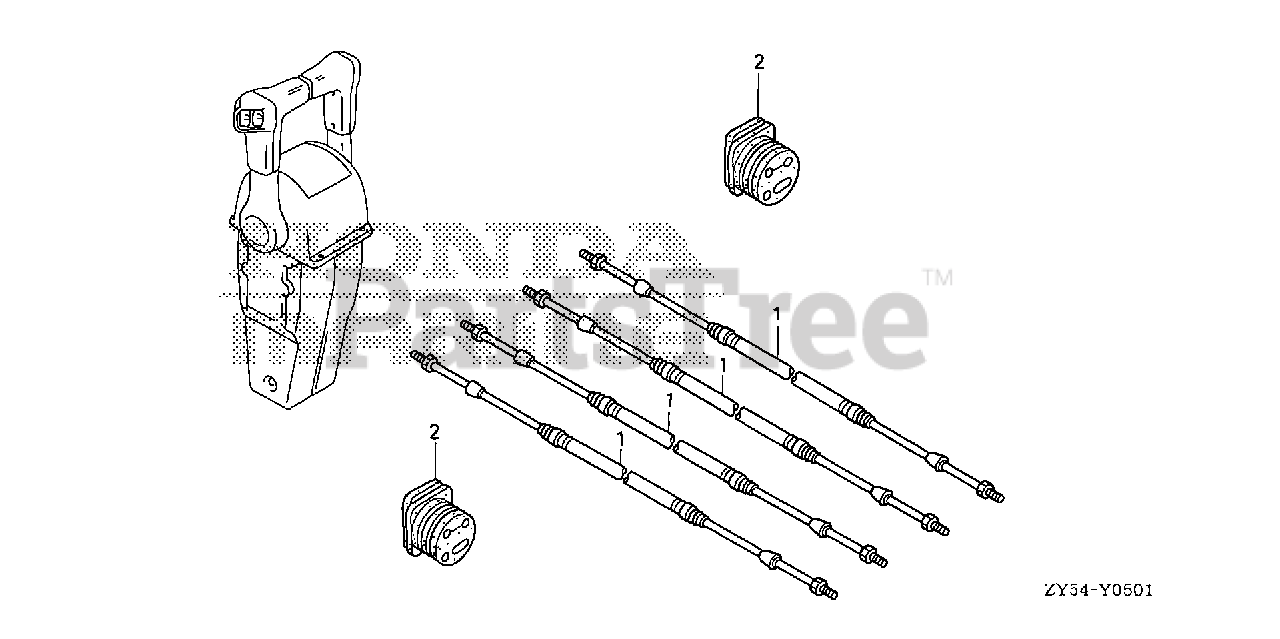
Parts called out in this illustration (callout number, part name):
1	CABLE ASSY., PUSH-PULL (33C-5FT)
1	CABLE ASSY., PUSH-PULL (33C-6FT)
1	CABLE ASSY., PUSH-PULL (33C-7FT)
1	CABLE ASSY., PUSH-PULL (33C-8FT)
1	CABLE ASSY., PUSH-PULL (33C-9FT)
1	CABLE ASSY., PUSH-PULL (33C-10FT)
1	CABLE ASSY., PUSH-PULL (33C-11FT)
1	CABLE ASSY., PUSH-PULL (33C-12FT)
1	CABLE ASSY., PUSH-PULL (33C-13FT)
1	CABLE ASSY., PUSH-PULL (33C-14FT)
1	CABLE ASSY., PUSH-PULL (33C-15FT)
1	CABLE ASSY., PUSH-PULL (33C-16FT)
1	CABLE ASSY., PUSH-PULL (33C-17FT)
1	CABLE ASSY., PUSH-PULL (33C-18FT)
1	CABLE ASSY., PUSH-PULL (33C-19FT)
1	CABLE ASSY., PUSH-PULL (33C-20FT)
1	CABLE ASSY., PUSH-PULL (33C-21FT)
1	CABLE ASSY., PUSH-PULL (33C-22FT)
1	CABLE ASSY., PUSH-PULL (33C-23FT)
1	CABLE ASSY., PUSH-PULL (33C-24FT)
1	CABLE ASSY., PUSH-PULL (33C-25FT)
1	CABLE ASSY., PUSH-PULL (33C-26FT)
1	CABLE ASSY., PUSH-PULL (33C-27FT)
1	CABLE ASSY., PUSH-PULL (33C-28FT)
1	CABLE ASSY., PUSH-PULL (33C-29FT)
1	CABLE ASSY., PUSH-PULL (33C-30FT)
1	CABLE ASSY., PUSH-PULL (33C-31FT)
1	CABLE ASSY., PUSH-PULL (33C-32FT)
2	GROMMET, CASE (LOWER) (B)
